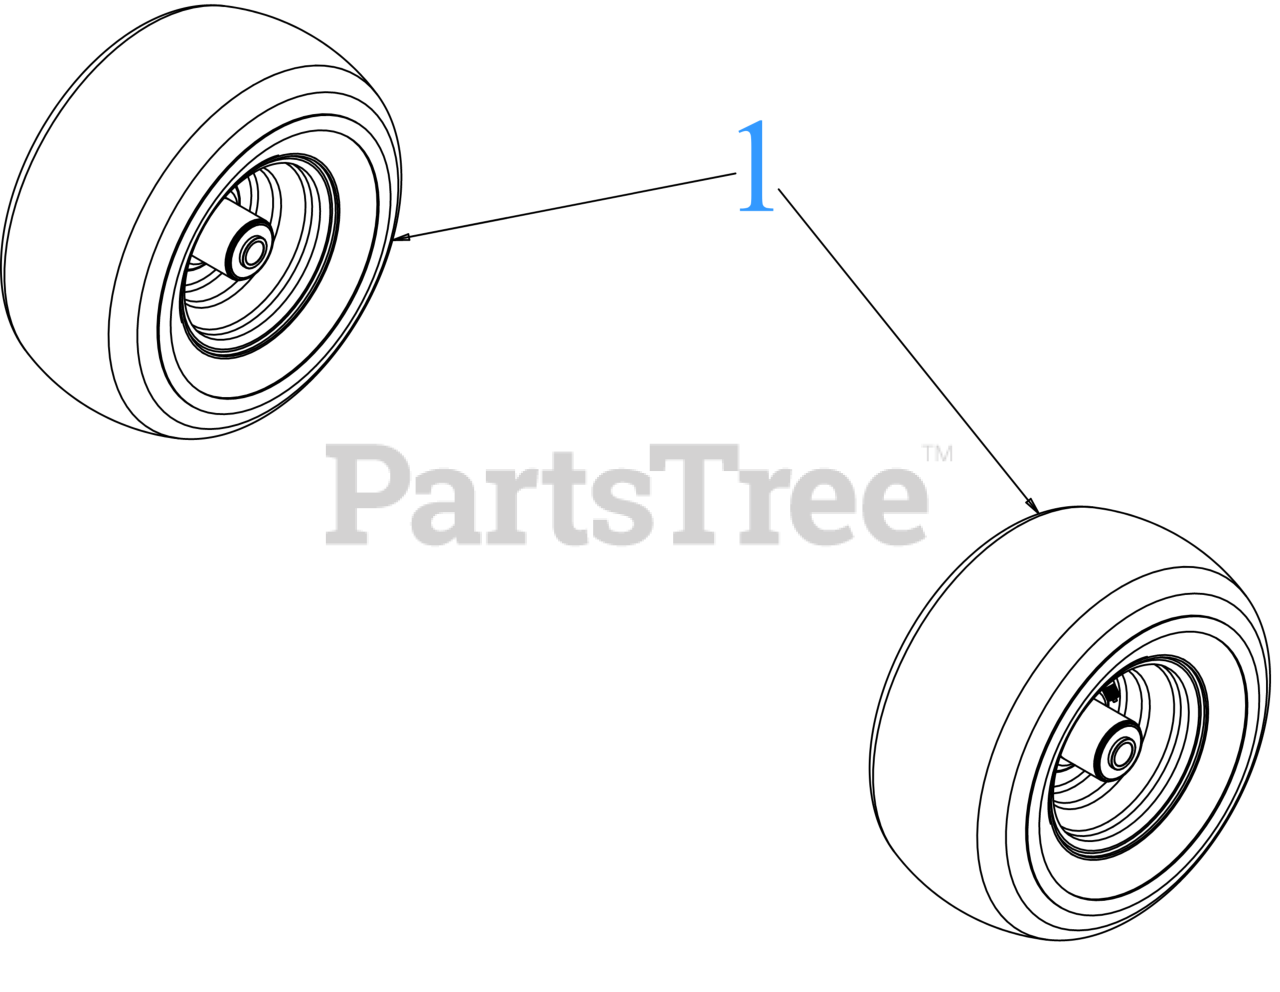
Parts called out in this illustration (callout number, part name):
1	CASTER WHEEL ASSEMBLY
1	TUBELESS AIR VALVE
1	SEALED BALL BEARING
